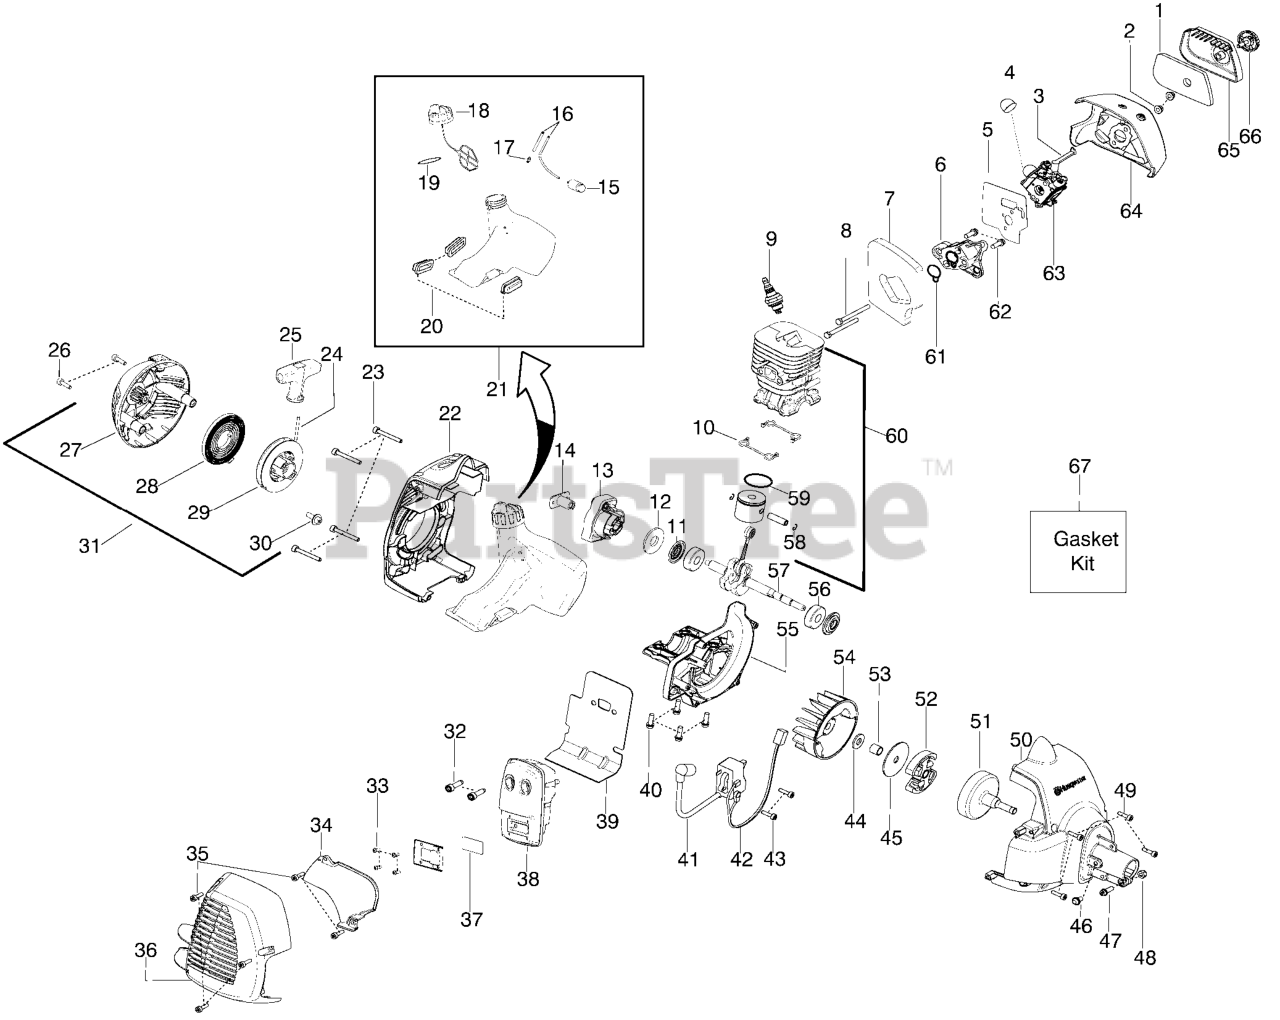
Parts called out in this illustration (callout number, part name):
2	Nut - Carb. Screw
3	Lever - Choke
4	Bulb - Purge
5	Kit-Carb. Gasket
6	Adaptor - Carb.
7	Foam - Gasket (kit)
9	Plug - Spark (RCJ-6Y)
10	Seal - Cylinder (kit)
11	Seal - Crankshaft (kit)
12	Washer
13	Assy - Starter Cup
14	Coupling - Starter
15	Assy - Fuel Filter
16	Kit - Fuel Line
17	Fitting - Fuel Line
18	Assy - Cap w/ret.
19	O-Ring - Fuel Cap (kit)
20	Isolator - Fuel Tank
21	Kit - Fuel Tank
22	Shroud - Rear
24	Kit - Rope
25	Handle - Starter
27	Starter Hsg. w/eyelet
28	Kit - Starter Spring
29	Kit - Starter Pulley
31	Assy-Starter Hsg.
32	Bolt - Muffler
33	Screw
34	Shield - Heat
36	Guard - Muffler
37	Kit – Spark
38	Kit - Muffler
39	Gasket-Paper Met.(kit)
41	Module
42	Assy - Leadwire
45	Washer - Clutch
50	Assy - Fan Housing
51	Assy - Clutch Drum
52	Kit - Clutch Assy.
55	Crankcase - cast
57	Crankshaft - Assy
58	Retainer - Piston Pin
59	Ring - Piston
60	Kit - Cyl./Piston
61	Seal - adaptor (kit)
62	Screw
63	Kit - Carb.
64	Airbox
65	Cover - Air Box
66	Assy - Knob
67	Kit - Gasket
